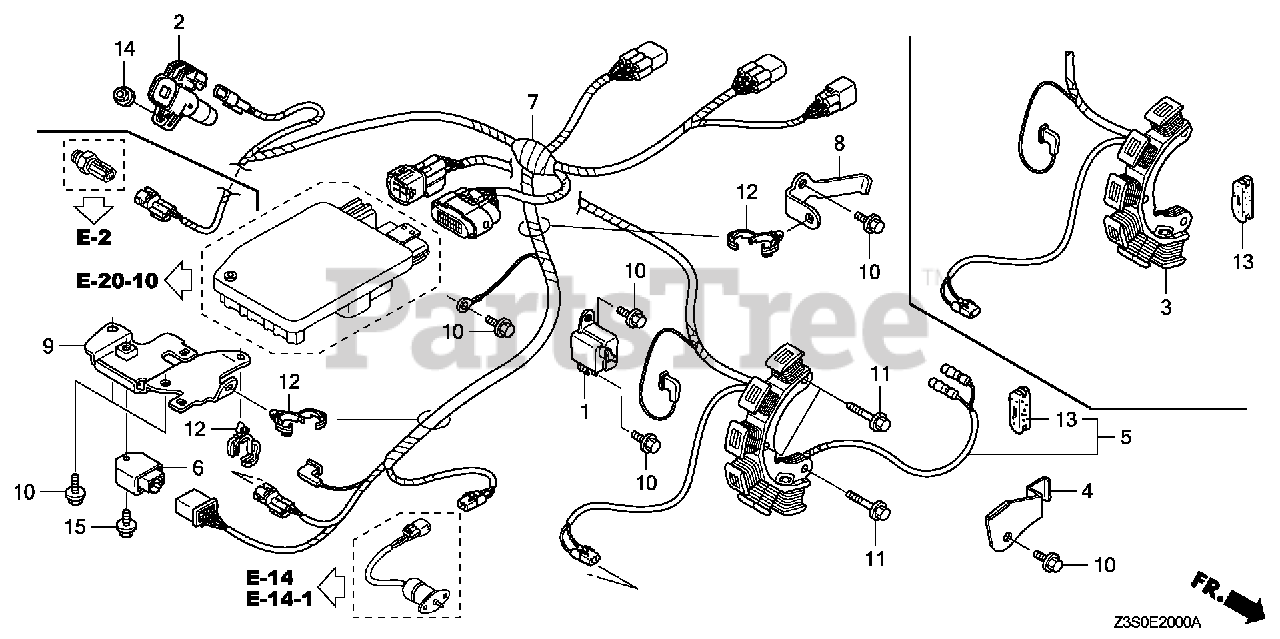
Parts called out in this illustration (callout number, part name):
1	COIL ASSY., PULSER
2	COIL, IGNITION
4	CLAMP, WIRE
5	COIL ASSY., CHARGE (3A)
6	RECTIFIER ASSY.
7	WIRE HARNESS ASSY., ENGINE
8	BRACKET, HARNESS CLIP (A)
9	BRACKET, HARNESS (C)
10	BOLT, FLANGE (6X14) (CT200)
11	BOLT, FLANGE (6X32) (CT200)
12	CLIP, HARNESS
13	GROMMET, CORD
14	NUT, FLANGE (6MM)
15	BOLT, FLANGE (6X12)
